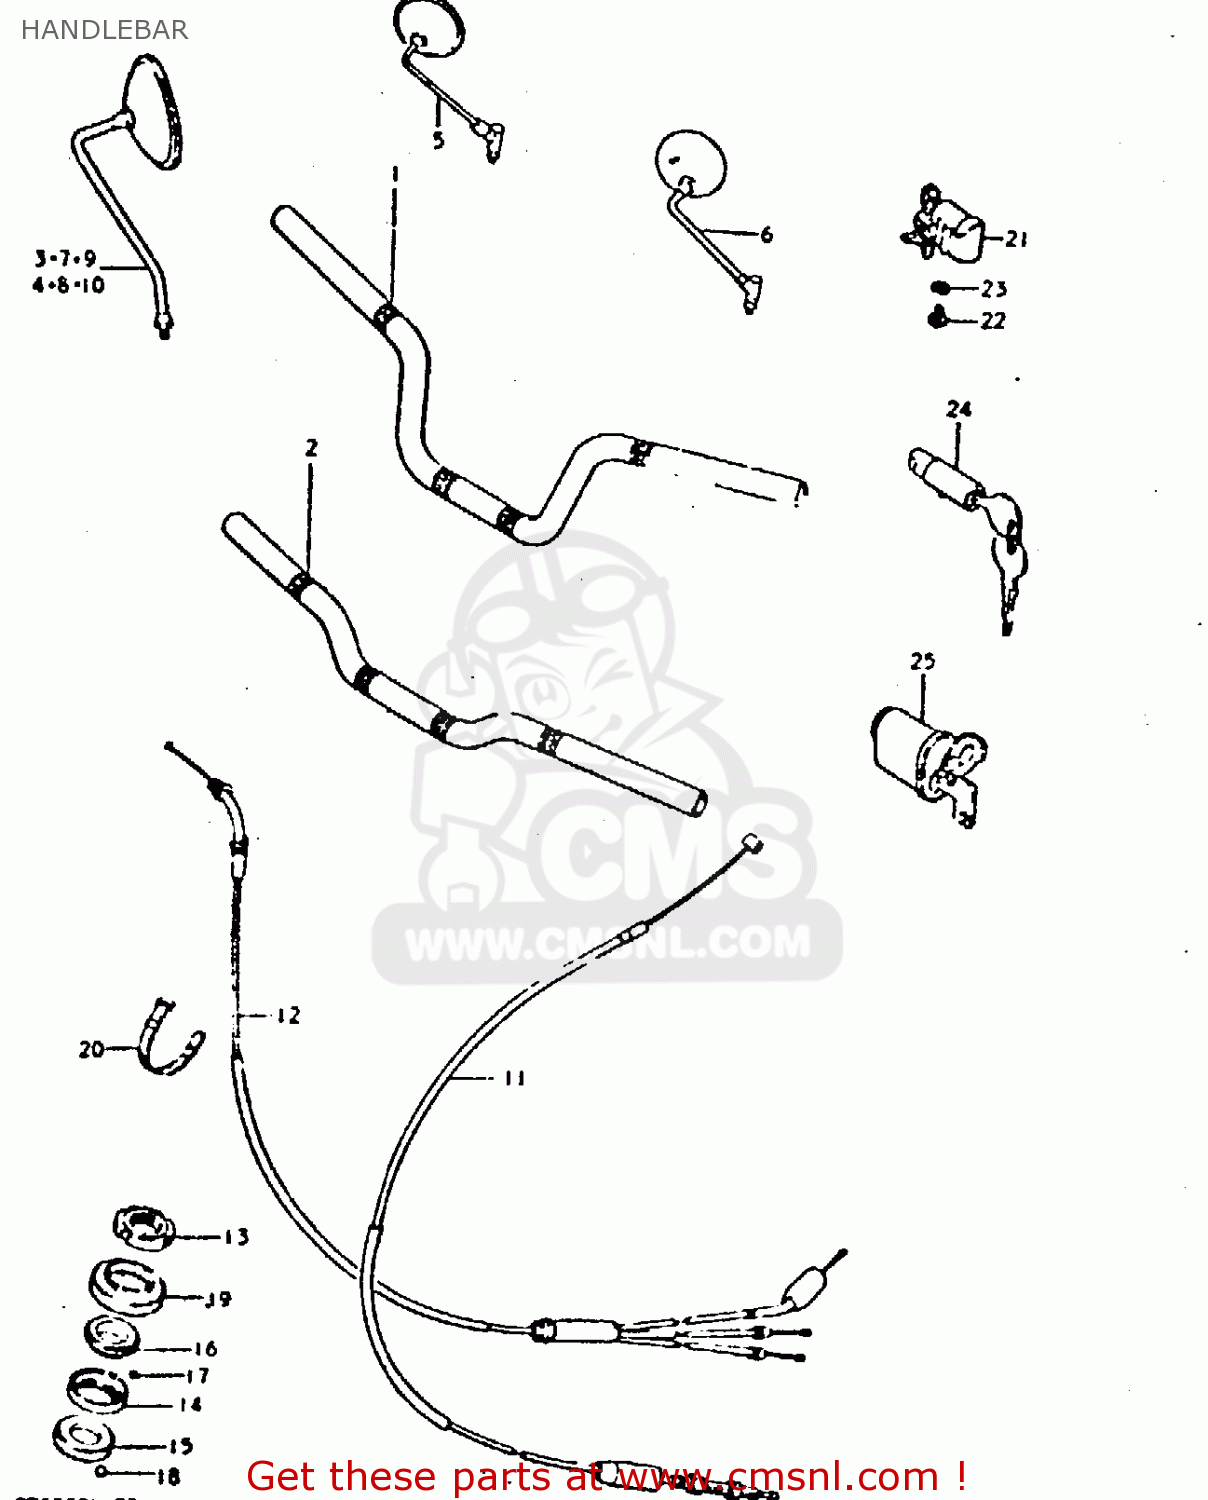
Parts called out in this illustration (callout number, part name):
1	HANDLEBAR
2	HANDLEBAR
5	MIRROR ASSY,RH
11	CABLE, CLUTCH (FLAT)
12	CABLE, THROTTLE (FLAT)
13	NUT,STEERING STEM(25X44X10)
14	RACE,STEERING INNER UPR
15	LACE,STEERING INNER LWR
16	RACE,STEERING OUTER UPR
17	BALL
18	BALL
19	DUST SEAL,STEERING UPR
20	CLAMP(L:120)
21	LOCK ASSEMBLY,STEERING
22	SCREW
23	LOCK WASHER
